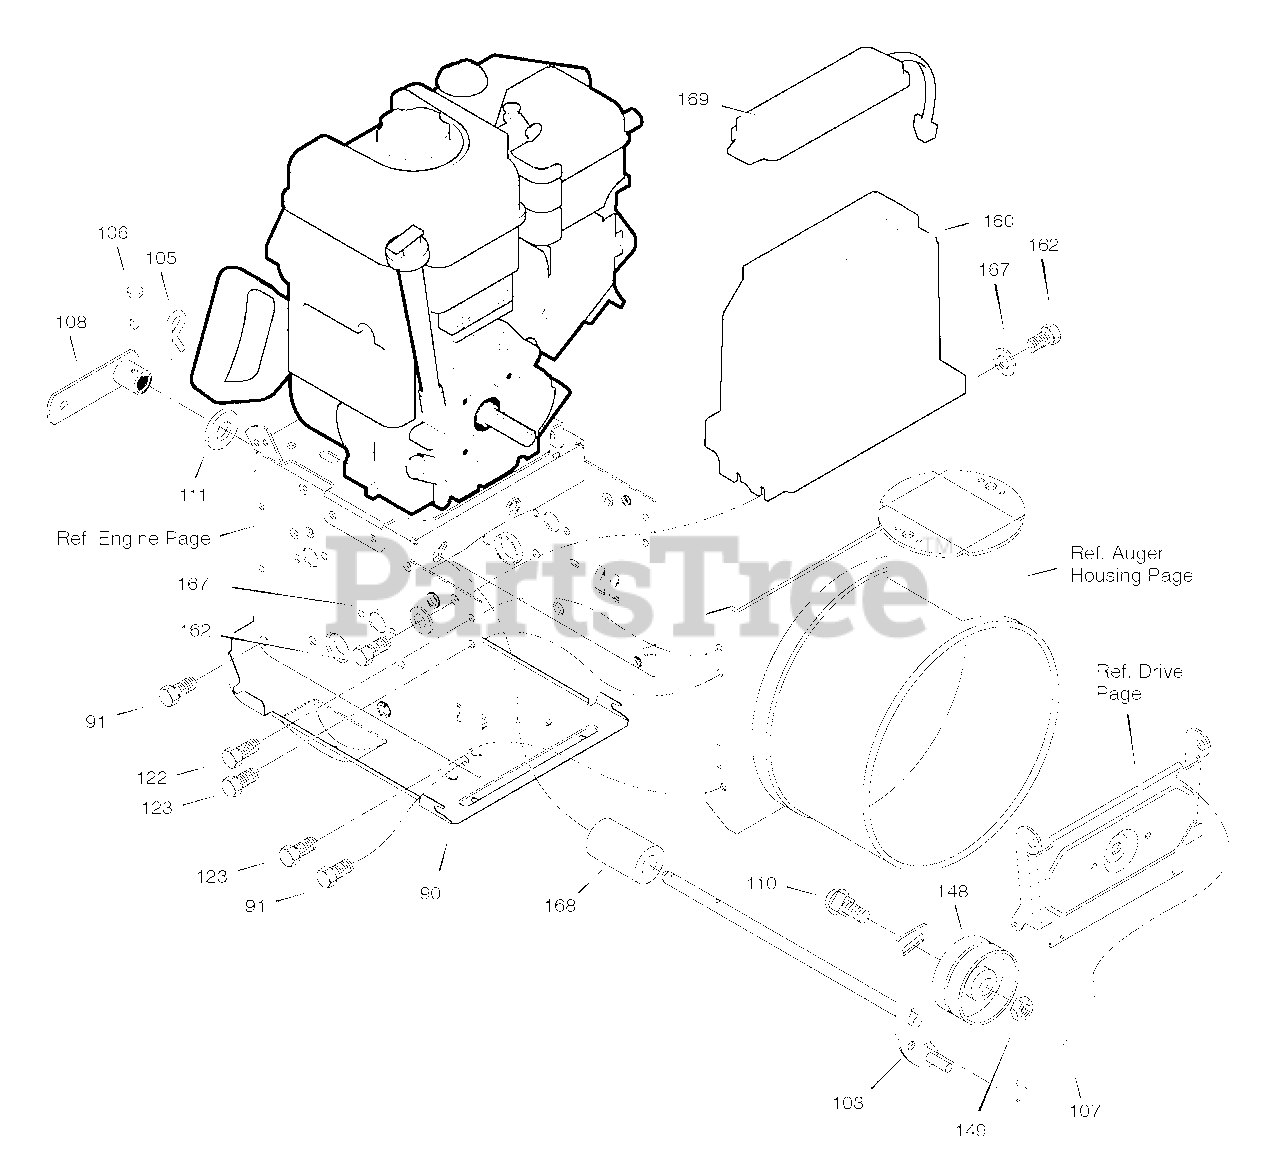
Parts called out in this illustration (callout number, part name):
90	COVER, BOTTOM
91	SCREW, 1/4-20X .63
103	IDLER ASSEMBLY, AUGER
105	PIN, HAIR .38DIAX1.64LG
106	PIN, CLEVIS 3/16" DIA
107	SPRING, TENSION
108	ASSY., SPRING ATTACH
110	BOLT, 3/8-16X1.25 CARR.
111	WASHER, FLAT
122	SCREW, TAP 5/16-18 X .75
123	SCREW, TAP 5/16-18 X .50
148	PULLEY, IDLER
149	NUT, JAM 3/8-16
160	COVER, BELT
162	SCREW, TAP
167	WASHER, FLAT
168	SPACER, AUGER BRACKET
169	LID, TOOL BOX
